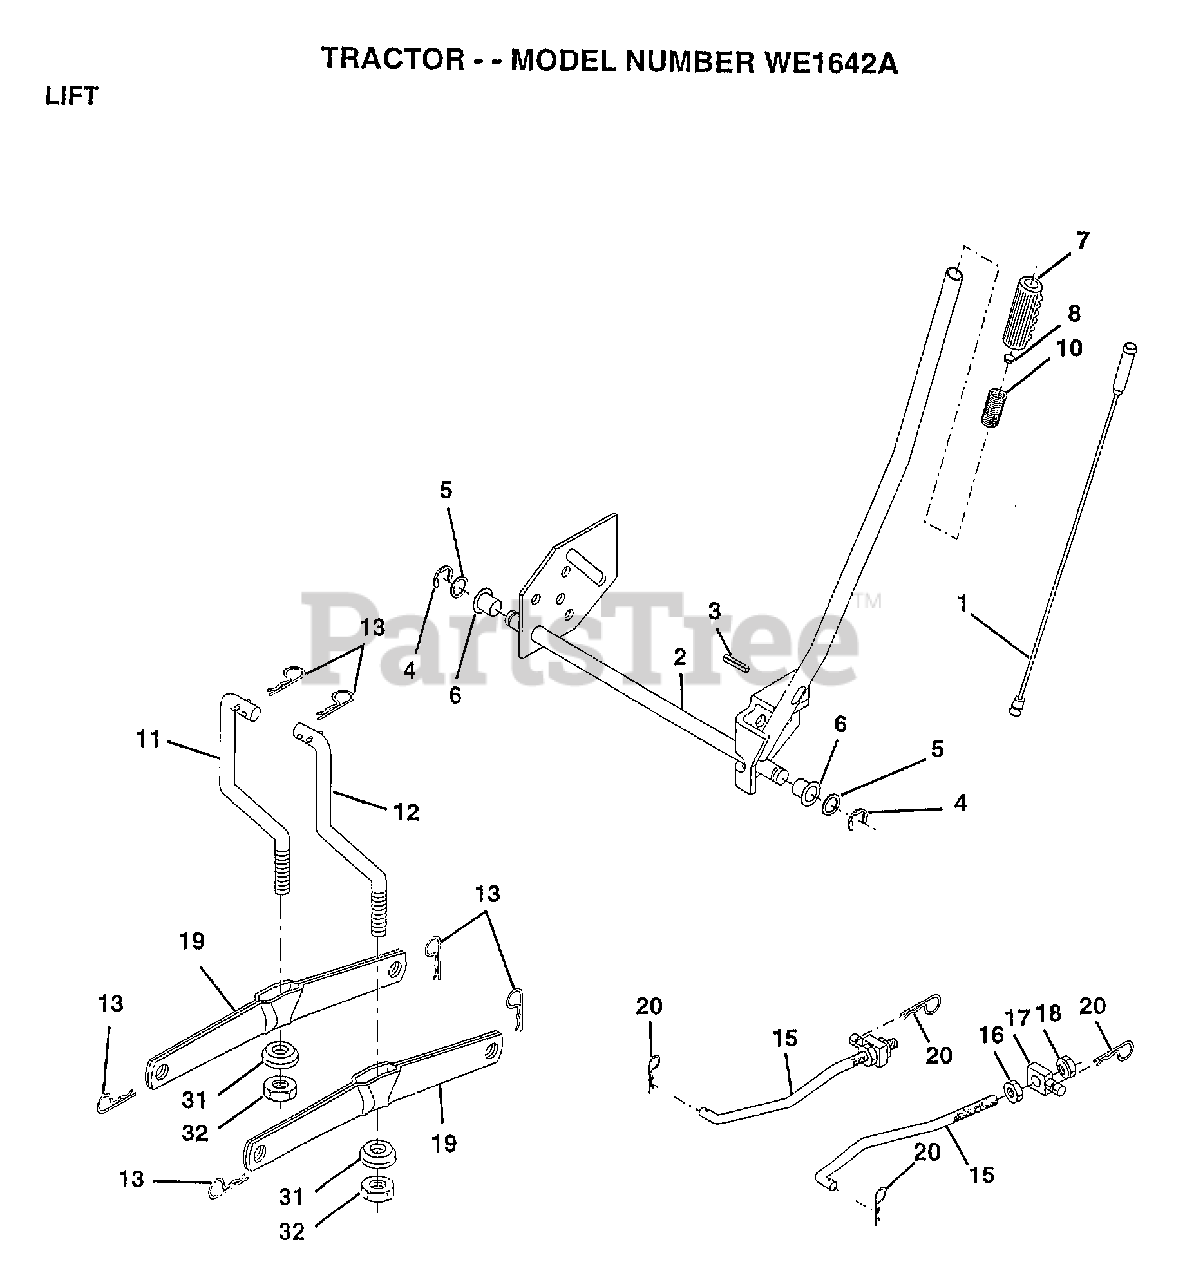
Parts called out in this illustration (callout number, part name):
1	WIRE ASM
2	SHAFT.LIFT.ASM.RH
3	PIN-GROOVE LT
5	WASHER
6	NYLON BEARING
7	GRIP
15	LINK.FRONT
16	NUT
17	TRUNION
18	NUT.LK.W/WSH.1/2.
19	ARM SUSP REAR
20	RETAINER.SPRING
31	BEARING PVT LH
32	NUT.CROWNLOCK.3/8
